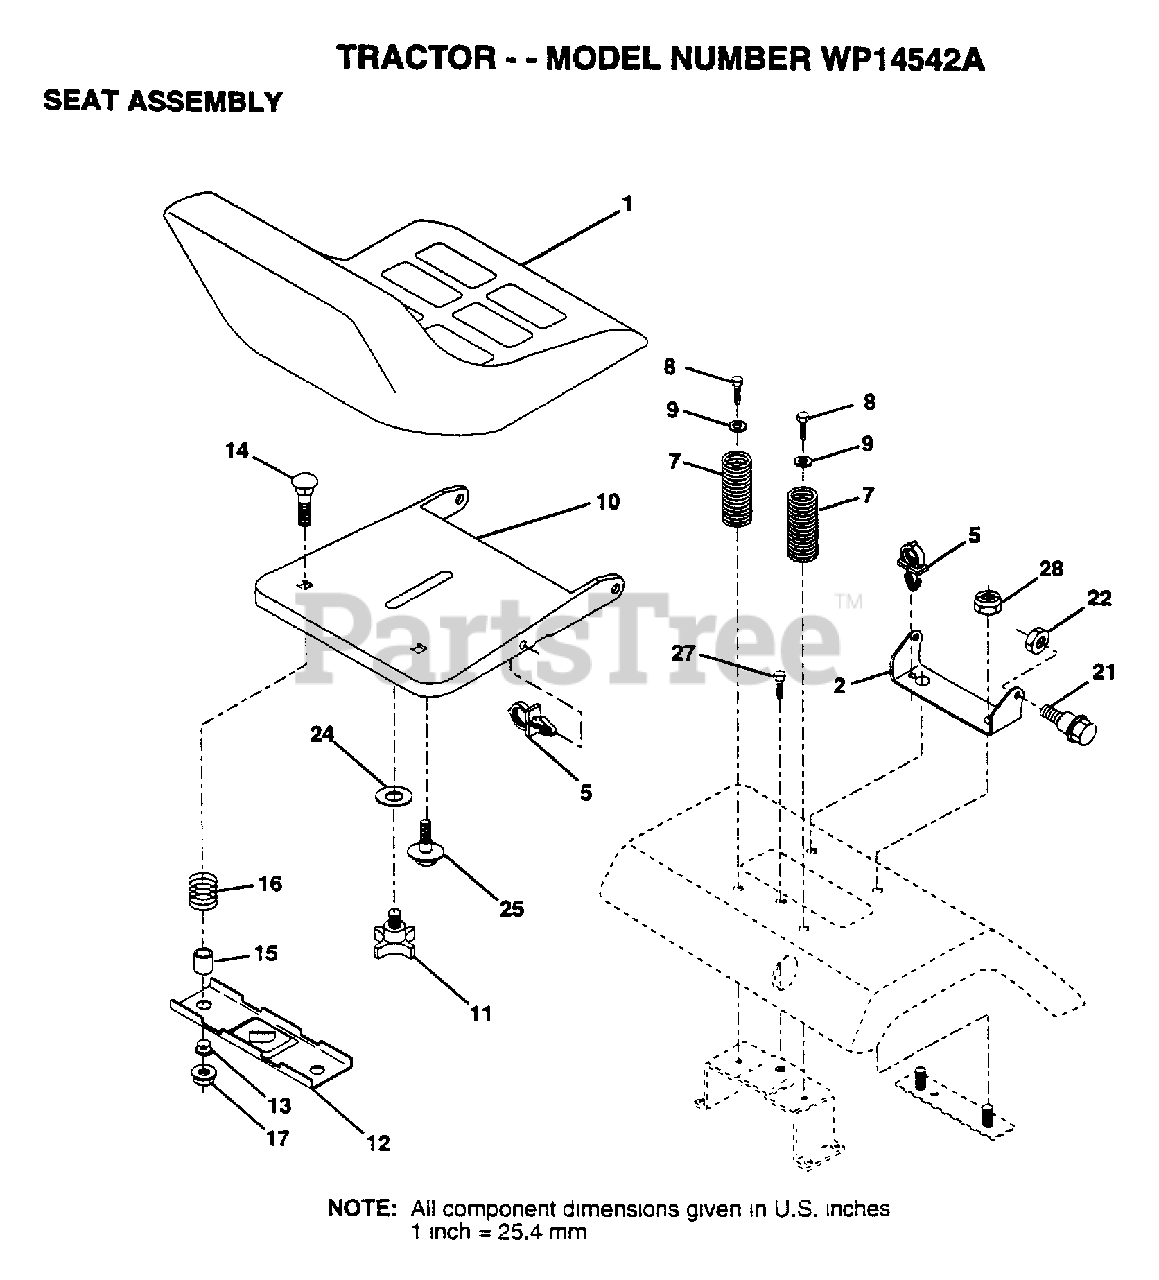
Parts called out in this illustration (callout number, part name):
2	BRACKET PVT SEAT
5	CLIP.PUSH-IN.HING
7	SPRING COMPRESSIO
8	SCREW LT
9	WASHER
11	"KNOB 1/2"" YT"
12	BRKT SWITCH
13	BUSHING
15	SPLIT SPACER
16	SPRING
21	BOLT.SHLD.5/16-18
22	NUT
24	WASHER
25	"BOLT,SHOULDER"
27	SCREW LT
